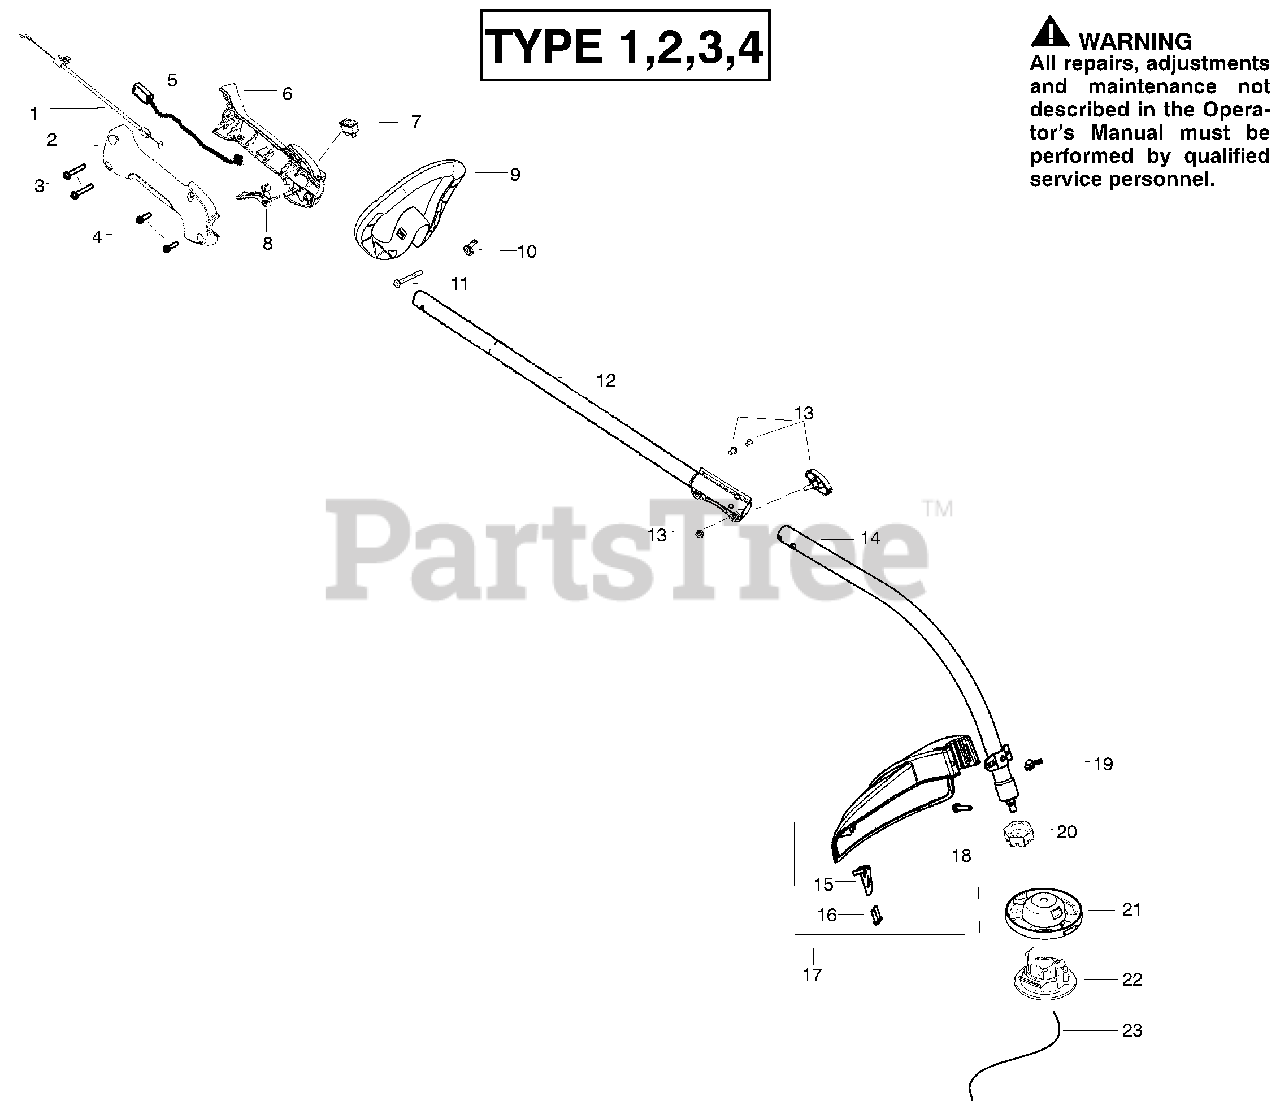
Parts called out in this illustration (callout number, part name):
1	ASSY THROTTLE CABLE
2	HOUSING THROTTLE FAN
3	SCREW #10 PLASTITE 1.362
5	WIRE ASSY
6	HSG THROTTLE LH
7	Switch Kit
8	TRIGGER RED
9	HANDLE ASSIST 1"
10	WINGNUT, TYPE 2
11	BOLT 1/4-20 X 2 SQUARE
12	KIT UPPER SHAFT BLACK
13	ASSY COUPLER BLACK
14	KIT LOWER SHAFT CURVED
15	LINE CUTTER
17	KIT SHIELD
18	BOLT, TYPE 2
19	WINGNUT, TYPE 2
20	DUST CUP
21	HEAD CUTTING FIX LINE
22	CAP FIXED LINE 6
23	ACCY WE.095 X 16.5" LINE 12PCS
